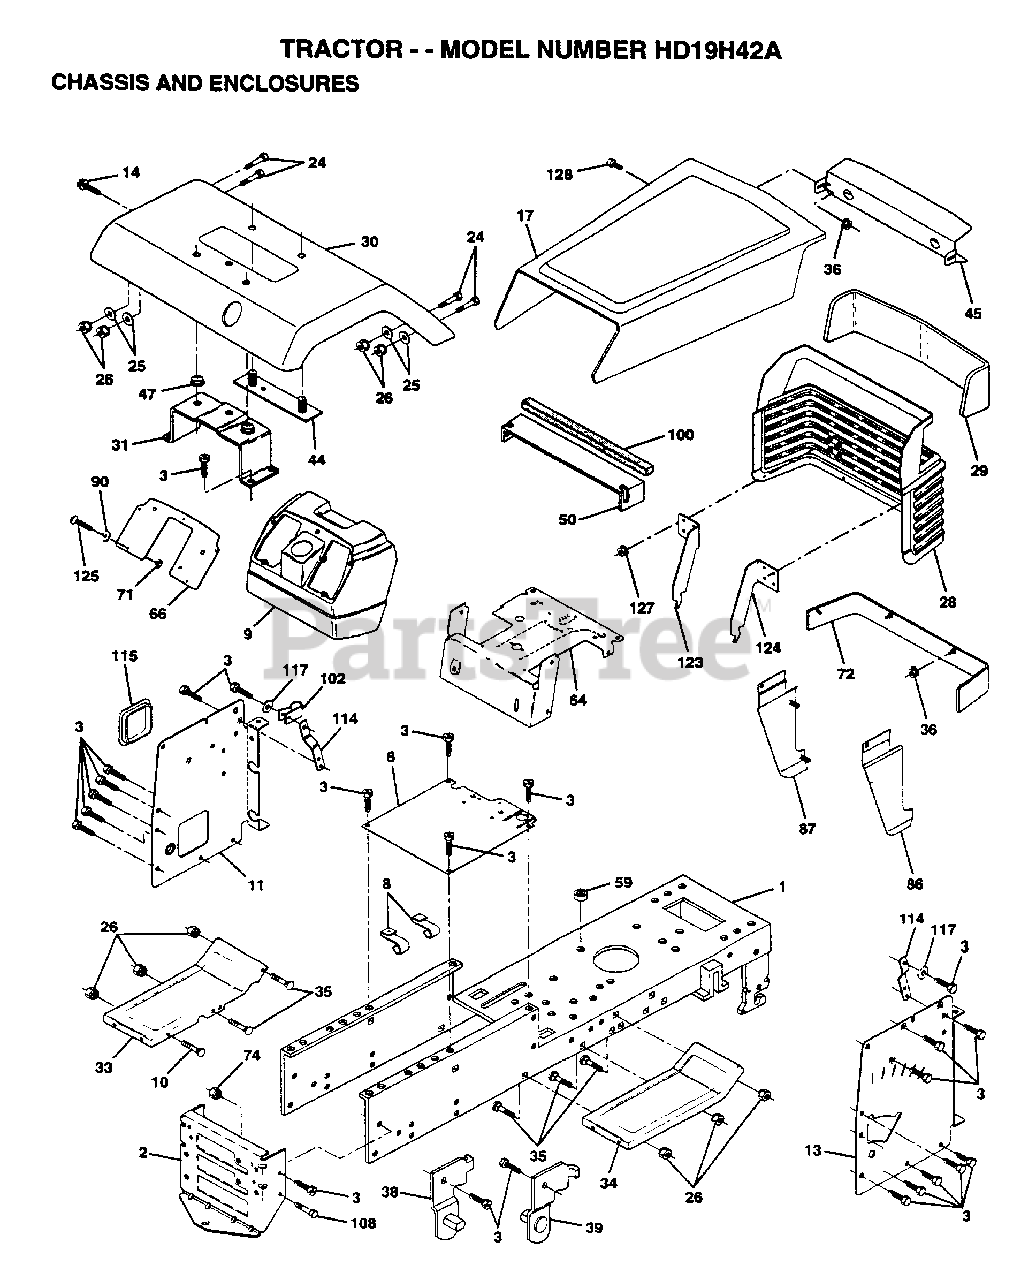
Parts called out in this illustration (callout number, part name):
1	CHASSIS.WLD.11GA
3	SCREW
8	"CLIP,INSULATOR"
9	DASH.PLASTIC.BLK
11	PANEL.DASH.LH.
13	PANEL.DASH.RH.NOT
14	SCREW LT
17	HOOD/GRILLE ASM
24	BOLT
25	WASHER
26	NUT
28	GRILLE ASM WELD
30	FENDER PNT
31	BRKT.ASM.FENDER
33	FOOTREST.LH.LT/GT
34	FOOTREST.RH.LT/GT
35	BOLT
36	PAL NUT LT
38	BRACKET ASM LH
39	BRACKET ASM RH
44	STRAP ASM FENDER
47	NUT-PUSH YT
66	PLATE.SLKSC.YT/GT
72	STRAP FENDER ASM
86	PANEL SIDE RH ASM
87	PANEL SIDE LH ASM
90	WASHER
102	CLIP T
114	BRACKET.SUPT.DASH
115	COVER ACCESS
117	WASHER.SERRATED.
124	BRACKET.PICK.RH
125	SCREW
127	PAL NUT
128	SCREW SPECIAL
